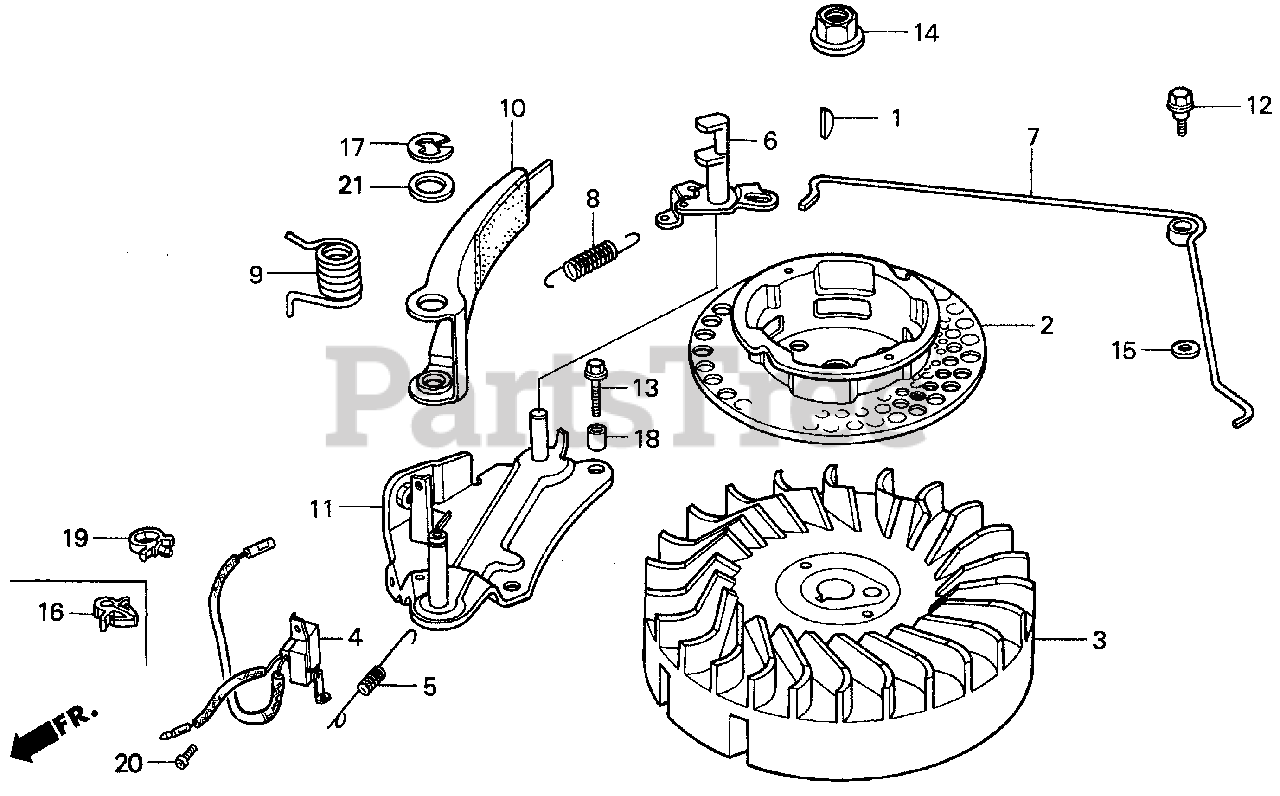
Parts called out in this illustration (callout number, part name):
1	KEY, SPECIAL WOODRUFF (25X18)
2	PULLEY, STARTER
3	FLYWHEEL
4	SWITCH ASSY., ENGINE STOP
5	SPRING, SWITCH CONTROL
6	CAM, BRAKE
7	ROD, THROTTLE RETURN
8	SPRING, BRAKE
9	SPRING, BRAKE RETURN
10	BRAKE
11	BASE, BRAKE
12	BOLT, FLANGE (6MM)
13	BOLT, FLANGE (6X23)
14	NUT, SPECIAL (14MM)
15	WASHER, DRUM STOPPER
16	CLIP, WIRE HARNESS
17	E-RING (10MM)
18	PIN, DOWEL (8X9)
19	CLIP, WIRE HARNESS
20	SCREW, PAN (4X8)
21	WASHER, FLAT (12MM)
